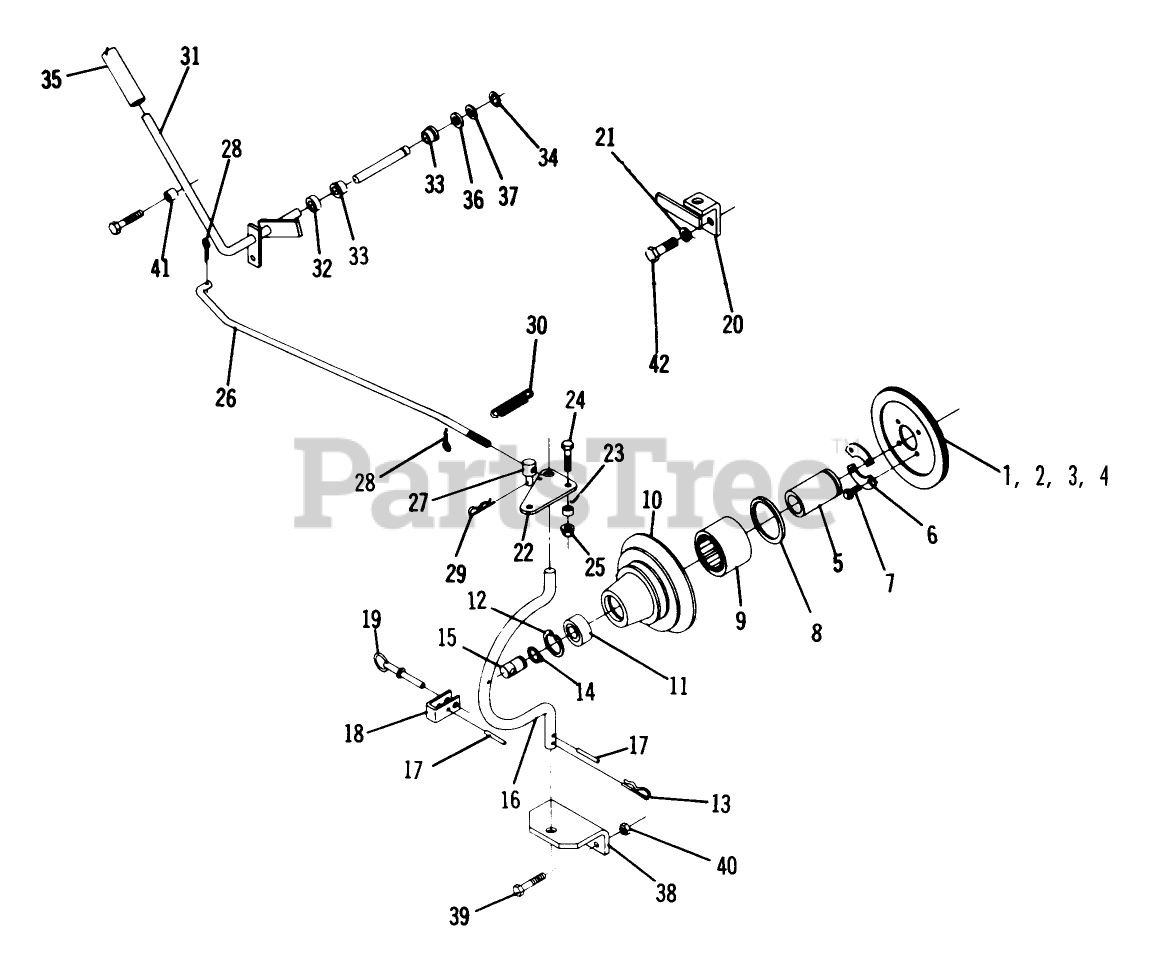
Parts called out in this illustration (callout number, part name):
1	Clutch Plate & Facing
2	Clutch Plate
3	Facing
4	RIVET-BRASS
5	RACE-BEARING
6	RETAINER
7	Bolt 1/4-20 x 5/8 Whizlock
8	SEAL-OIL
9	Seal
10	Housing-Clutch
11	Bearing
12	Ring-Snap
13	Hairpen
14	RING-SNAP, EXTERNAL
15	SHAFT-PTO
16	ROD HOUSING (NS)
17	PIN-SPIROL
18	Clevis
19	Pin
20	Bracket-Engine
21	Lockwasher 3/8
22	PLATE R
23	SPACER
24	Bolt-Hex 3/8-16 x 1
25	LOCKNUT-FLANGE
26	Clutch Rod
27	TRUNNION
28	Cotter Pin
29	Hairpin
30	Spring
31	Plug, Drain
32	SPACER
33	BUSHING-FLANGED
34	E Ring
35	GRIP
36	Washer
37	SHIM-WASHER
38	Axle
39	Bolt 3/8-16 x 1
41	Spacer
42	Bolt, 7/16 14 x 1
42	Bolt 3/8-16 x 1
